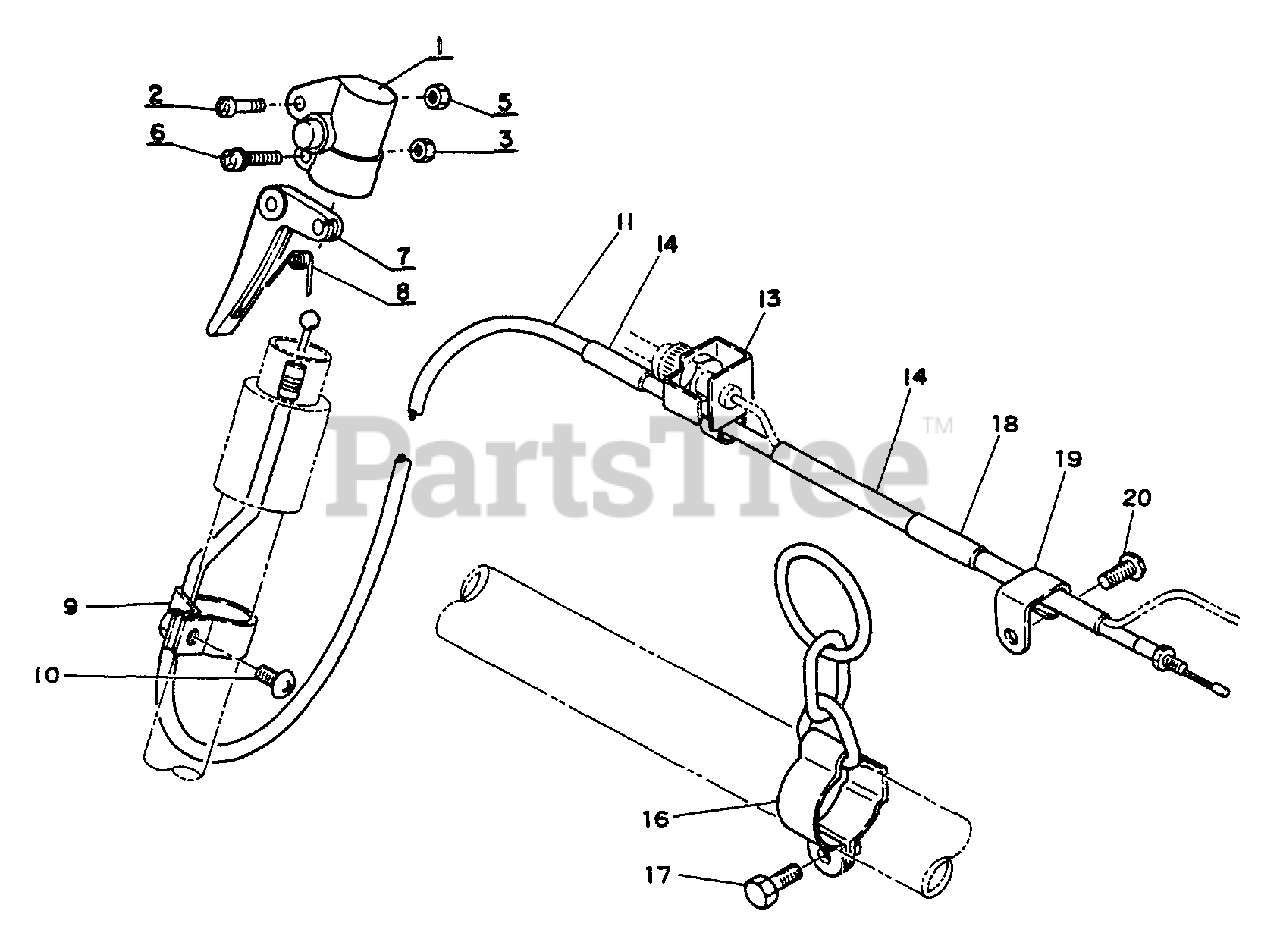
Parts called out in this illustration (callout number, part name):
1	CLAMP, THROTTLE CONTROL
2	SCREW - 5X30
5	LOCKNUT - 5
6	SCREW - 5X28
7	TRIGGER, THROTTLE
8	SPRING, TRIGGER
10	SCREW - 5X10
11	CABLE, THROTTLE
14	TUBE
16	HANGER KIT
17	BOLT - 5X12
18	TUBE
19	CLAMP
20	SCREW - 5X8
